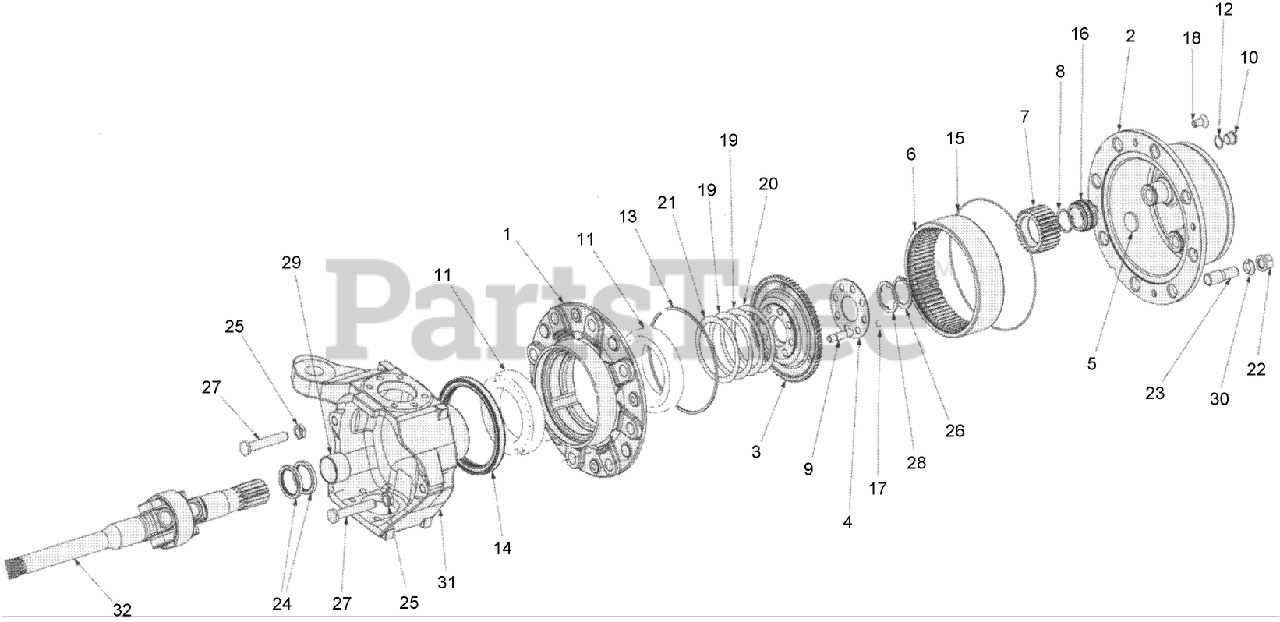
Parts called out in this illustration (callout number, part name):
1	HUB-WHEEL
2	HUB-Planetary
3	FLANGE-Crown
4	RING-Crown
5	SHIM-Crown Wheel
6	WHEEL-Crown
7	GEAR-Planetary
8	RING-SNAP
11	Bearing
12	WASHER-Copper
13	RING-Internal Retaining
15	O-RING
26	RING-SNAP
27	SCREW-Steering, End
28	SHIM-Crown
29	Bushing
30	WASHER-Elastic
31	JOINT-LH, Articulated
